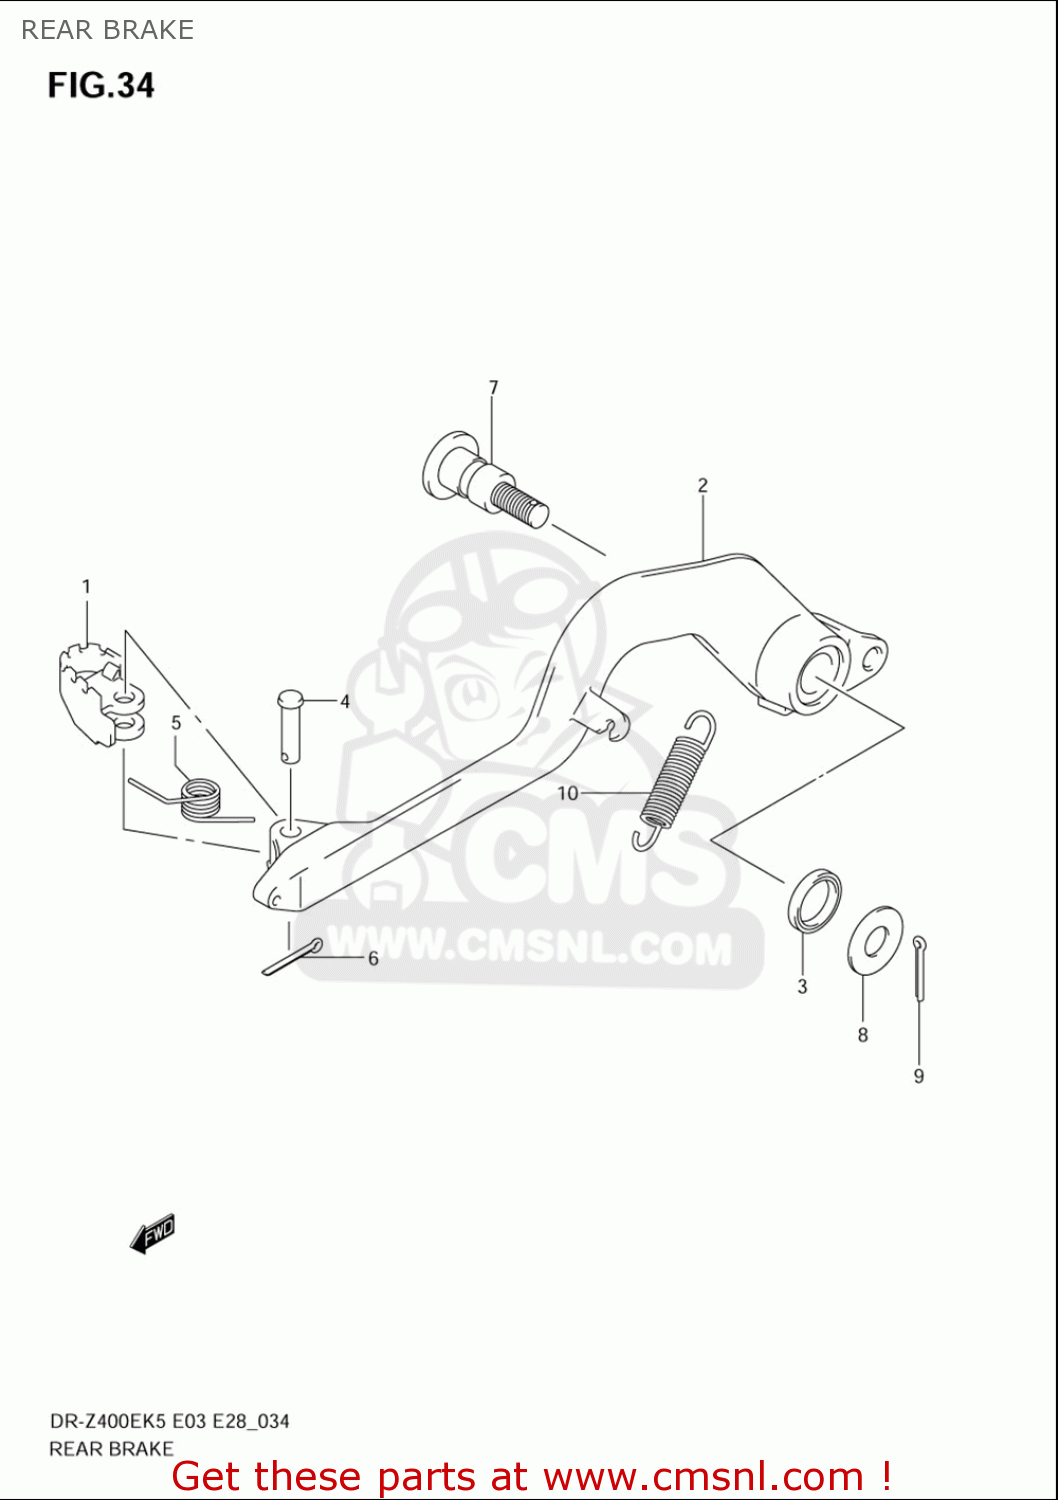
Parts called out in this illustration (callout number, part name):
1	PEDAL,BRAKE
2	ARM,BRAKE PEDAL
3	SEAL,OIL(15X21X3)
4	PIN(6X23.5)
5	SPRING
6	PIN
7	SHAFT,BRAKE PEDAL
8	WASHER
9	PIN
10	SPRING
